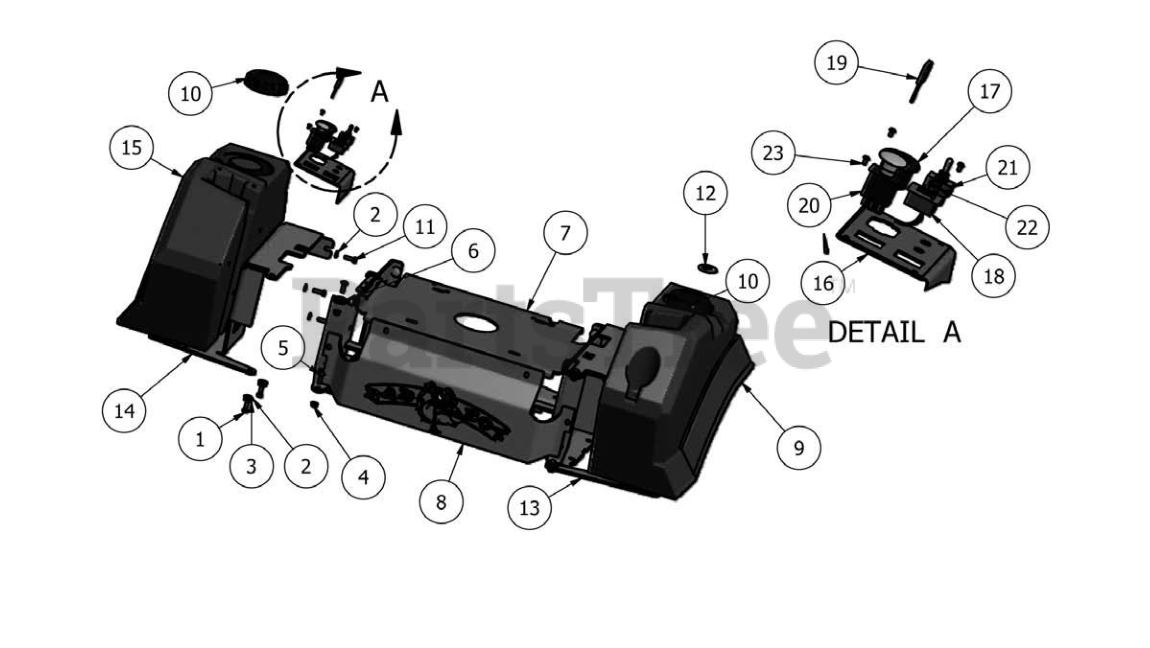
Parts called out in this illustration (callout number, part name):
1	5/16-18 x 1 Grade 5 Hex bolt Zinc
2	5/16 Flat washer
3	5/16 Lock Washer Zinc
4	5/16-18 Nylon Insert Flange Nut Zinc Orange Nylon
5	5/16-18 x 1 Carriage Bolts Zinc
6	.360ID Plastic Washer
7	Seat Plate
8	Cooler Cover
11	5/16" x 1" Hex Bolt
12	Fuel Gauge and Grommet
13	Right Tank Aupport
14	Left Tank Support
15	Right Tank
16	Control Panel
17	Ignition Switch
18	Tachometer
19	Ignition Key
20	PTO Engager
21	Deck Lift Joystick
23	10-24 X 5/8" Buttonhead Bolt
